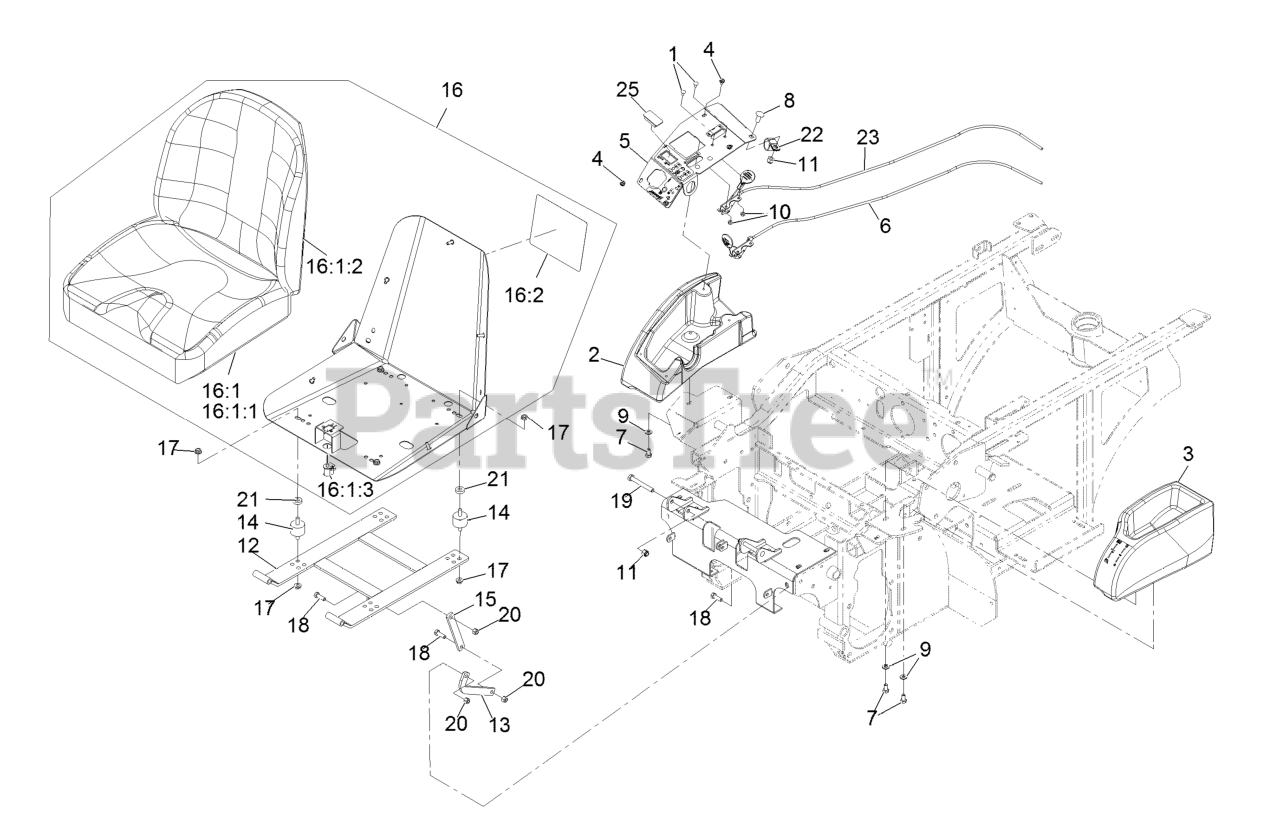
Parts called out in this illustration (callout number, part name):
1	BOLT-CARR
2	CONSOLE-RH
4	SCREW-PPH
5	CONTROL PANEL ASM
6	CABLE-THROTTLE
7	SCREW-HH
8	SCREW-CARR
9	WASHER-PLAIN
10	NUT-LOCK, NI
11	NUT-LOCK, NI
12	FRAME-SEAT
13	LINK-SEAT STOP
14	MOUNT-VIBRATION, RUBBER
15	LINK-SEAT
16:1	Asm-Seat
16:1:1	ASM-SEAT BOTTOM CUSHION
16:1:2	CUSHION,SEAT BACK
16:1:3	SWITCH-BAIL
16:2	DECAL-SERVICE AID
18	SCREW-HH
19	SCREW-CARR
20	NUT-LOCK, NI
21	SPACER
22	CLIP-LOOM
23	CABLE-CHOKE
25	PLUG-HOLE
